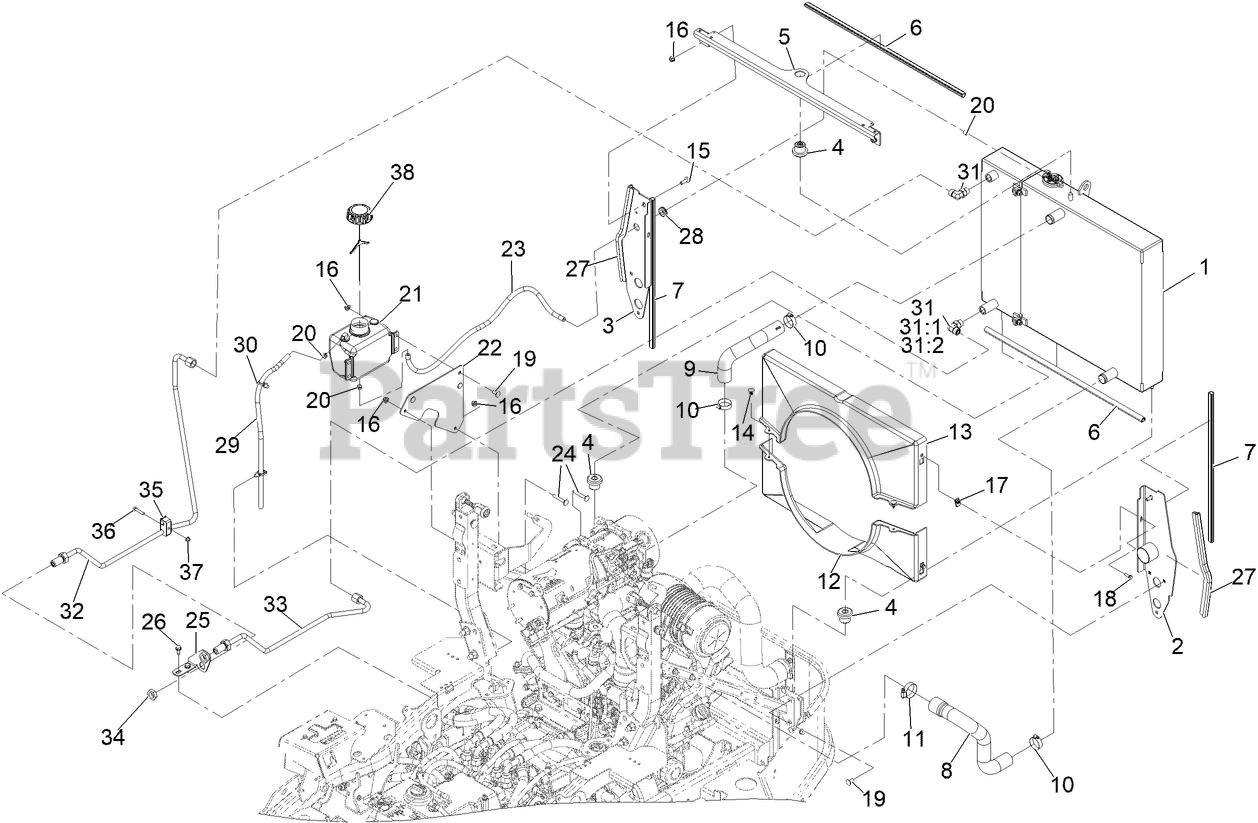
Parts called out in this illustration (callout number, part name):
1	COOLING ASM
2	SUPPORT-RADIATOR, LH
3	SUPPORT-RADIATOR, RH
4	MOUNT-ISOLATOR
5	BRACKET-COOLING, TOP
6	SEAL-BULB
7	SEAL-BULB
8	HOSE-RADIATOR, LOWER
9	HOSE-RADIATOR, UPPER
10	CLAMP-HOSE
11	CLAMP-HOSE
12	SHROUD-BOTTOM
13	SHROUD-TOP
14	PLUG-PLASTIC
15	SCREW-HHF
16	NUT-HF, NI
18	SCREW-HWH
19	SCREW-CARR
20	CLAMP-HOSE
21	TANK-OVERFLOW, W/CAP
22	BRACKET-BOTTLE
23	HOSE-FUEL
24	BOLT-CARR
25	BRACKET-BULKHEAD
26	SCREW-HWHTF
27	SEAL-BULB
28	GROMMET
29	HOSE-FUEL
30	CLIP-TIE
31	FITTING-ELBOW, 90 DEG
31:1	O-RING
31:2	O-RING
32	HYDRAULIC TUBE ASM
33	HYDRAULIC TUBE ASM
34	NUT-BULKHEAD
35	CLAMP-TWIN
36	SCREW-HH
37	NUT-HF
38	CAP-W/TETHER
